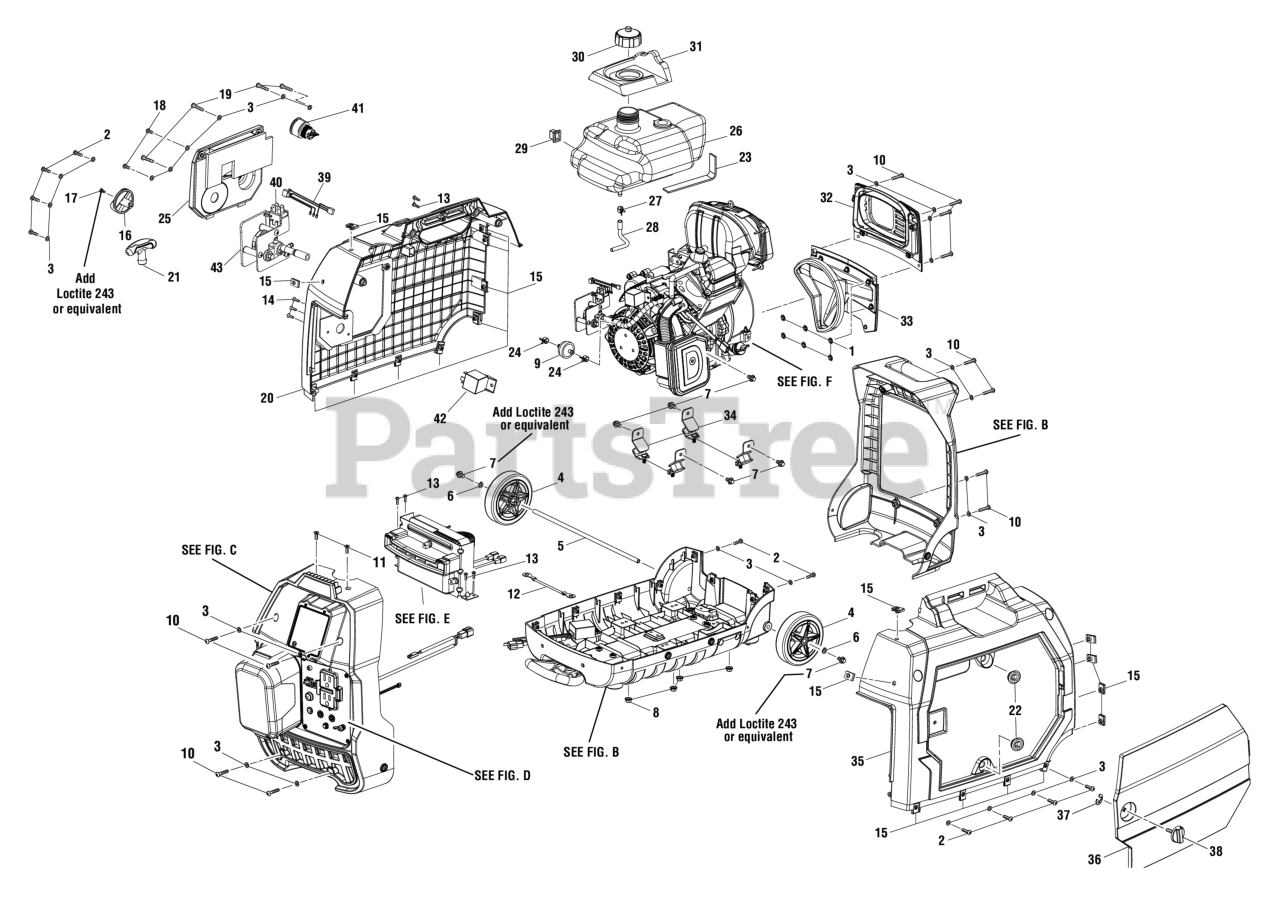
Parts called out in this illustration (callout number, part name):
1	Internal Tooth Strip Retainers
2	Screw (M5 x 20 mm, Button Soc. Hd.)
3	Washer (ID5.3 x OD10 x 1t)
6	Lock Washer (1/4 in.)
7	Bolt (M6 x 12 mm, Hex Hd.)
8	Lock Nut (M6)
9	Fuel Filter Inline (1/4 in.)
10	Screw (M5 x 25 mm, Button Soc. Hd.)
11	Screw (M5 x 16 mm, Flat Hd.)
12	Ground Wire
13	Screw (M4 x 12 mm, T15 Torx Pan Hd.)
14	Screw (M4 x 16 mm, Flat Hd.)
15	U-Clip (M5)
16	Control Knob
17	Screw (M4 x 10 mm)
18	Screw (M5 x 12 mm, T25 Torx Pan Hd.)
19	Screw (M5 x 30 mm, T25 Torx Pan Hd.)
20	Left Housing Assembly
21	Recoil Handle
23	Rubber Pad
24	Fuel Hose Clamp (9.5 mm)
25	Starter Cover Assembly
26	Fuel System Assembly
27	Clamp (D10 x 0.8 mm)
28	Fuel Hose (6mm and 4.5 mm)
29	Support (Fuel Tank)
30	Vented Fuel Cap
31	Overspill Guard
32	Upper Exhaust Panel Assembly (Inc. Key No. 3)
33	Lower Exhaust Panel Assembly
34	Engine Isolator (45 Degree)
35	Right Housing Assembly
36	Maintenance Cover Assembly
37	E-Clip (5 mm Shaft)
38	Lock Knob
39	Main Power Switch Wiring Harness
41	Start/Stop Button
42	14V DC - 80A Relay
43	Valve/Switch Starter Assembly (Inc. Key Nos. 39-40)
